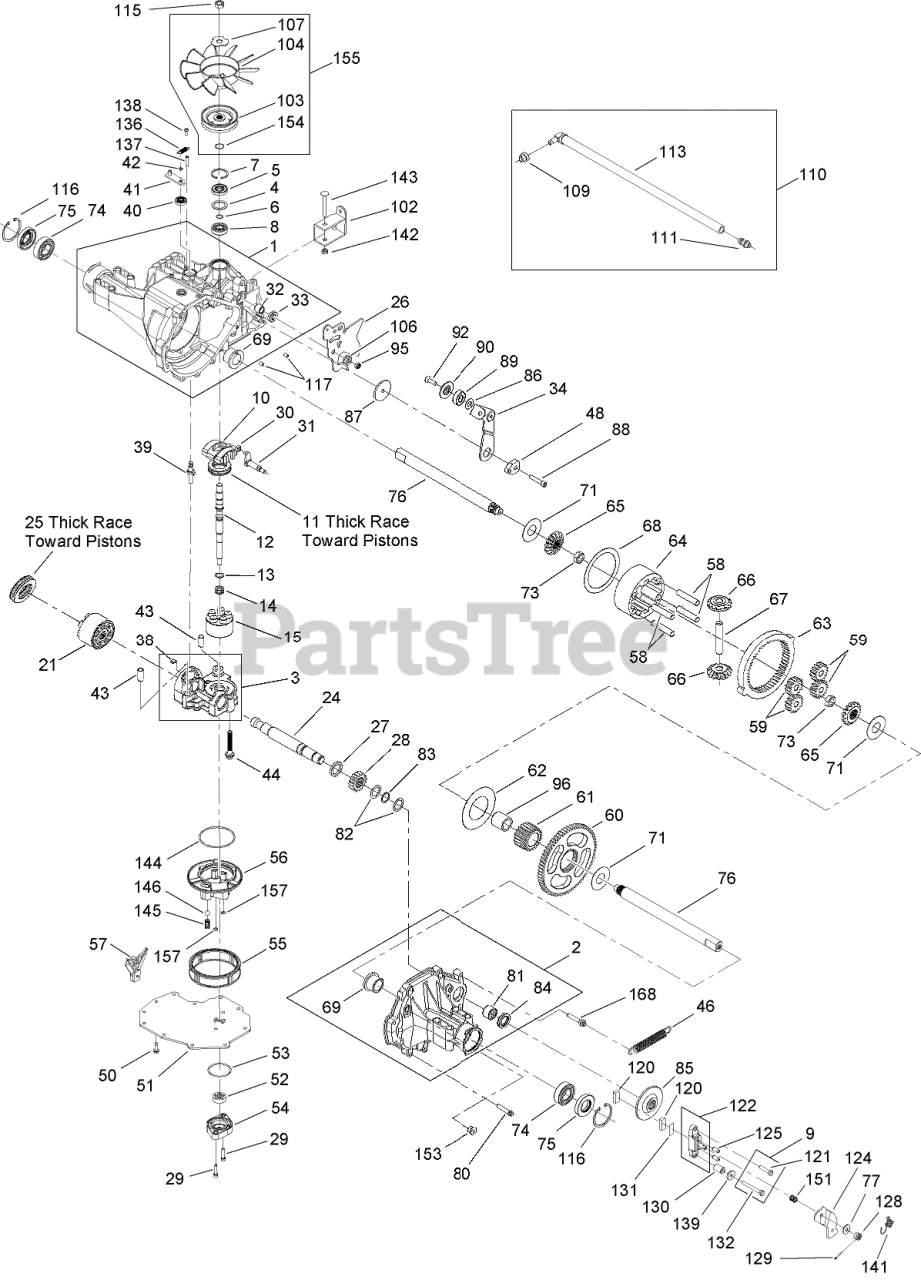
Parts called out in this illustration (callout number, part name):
102	BRACKET-TORQUE
103	PULLEY
104	FAN-BLADE, 10
106	SPACER-TRUNNION
107	WASHER-SLOTTED
109	BUSHING-VENT
110	FITTING KIT
111	CAP VENT ASM
113	90 DEGREE FITTING AND HOSE ASM KIT
115	NUT-HEX
116	RING-RETAINING
120	PUCK-BRAKE
121	BOLT-HEX
122	BRAKE YOKE ASM
124	ARM-BRAKE
125	PIN-BRAKE
128	NUT-CASTLE
129	PIN-COTTER
130	SPACER
131	PUCK-PLATE
132	BOLT-HEX
136	SPRING-BYPASS
137	PIN-SPRING
138	BOLT-TAP
139	WASHER
141	SPRING-ARM, BRAKE (BIAS)
142	NUT-HEX LOCK
144	O-RING
145	SPRING-RELIEF
151	SPRING-BRAKE, ANTI DRAG
153	PLUG-THREAD, STRAIGHT
154	RING-RETAINING
155	FAN AND PULLEY KIT
157	O-RING
168	BOLT-SHOULDER, TORX
